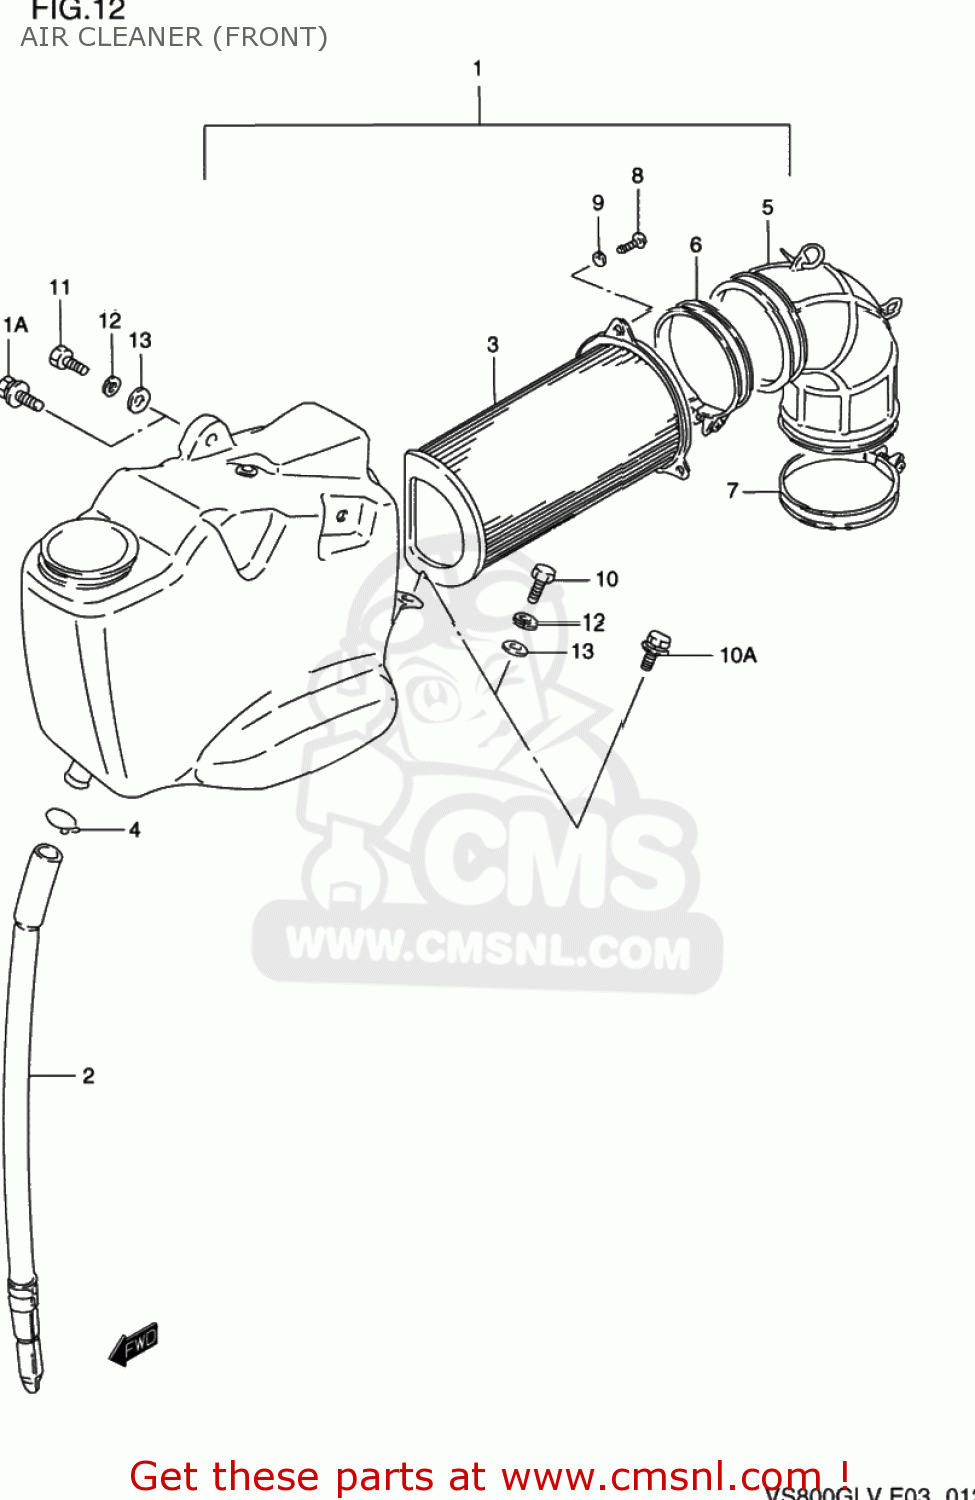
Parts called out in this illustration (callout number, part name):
1	CLEANER ASSY,AIR FR
2	DRAIN TUBE
3	FILTER ASSY
4	CLIP
5	TUBE,AIR CLEANER OUTLET
6	CLAMP
7	CLAMP
8	SCREW
9	LOCK WASHER
10	BOLT
10A	BOLT
11	BOLT
11A	BOLT, REAR
12	WASHER,LOCK
13	WASHER
